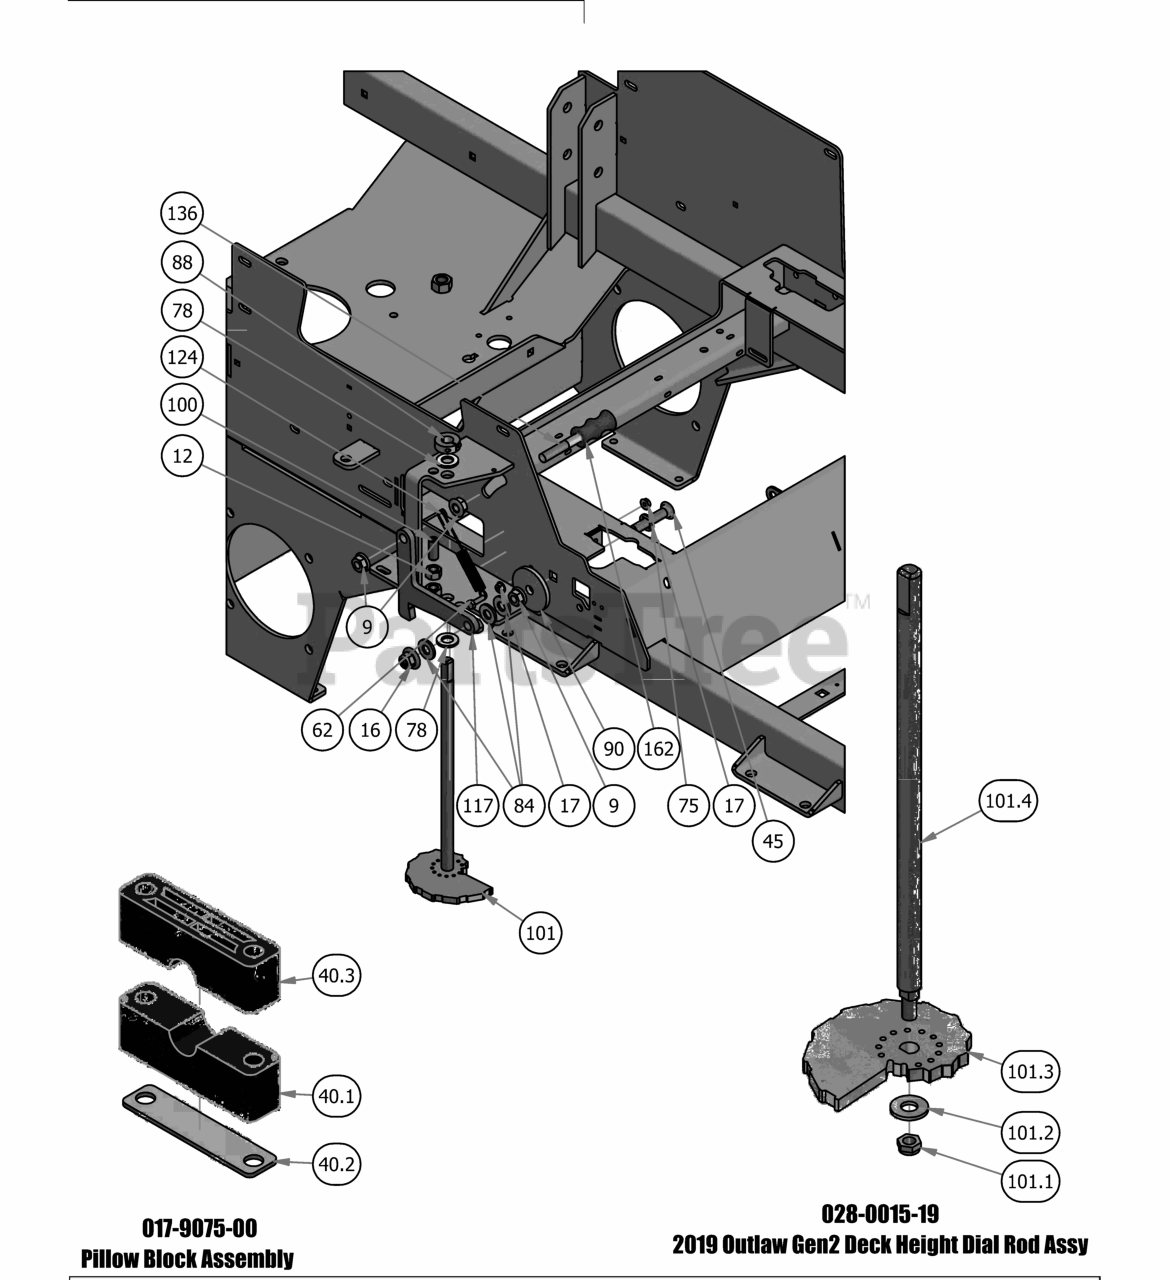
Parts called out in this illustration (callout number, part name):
40.1	Two Piece Pillow Block (Male)
40.2	Two Piece Pillow Block Strap
40.3	Two Piece Pillow Block (Female)
101.1	3/8-24 Nylon Insert jam locknut
101.2	3/8" Flat Washer
101.3	2019 Deck Height Cam
101.4	2019 Outlaw Gen2 Dial Rod
